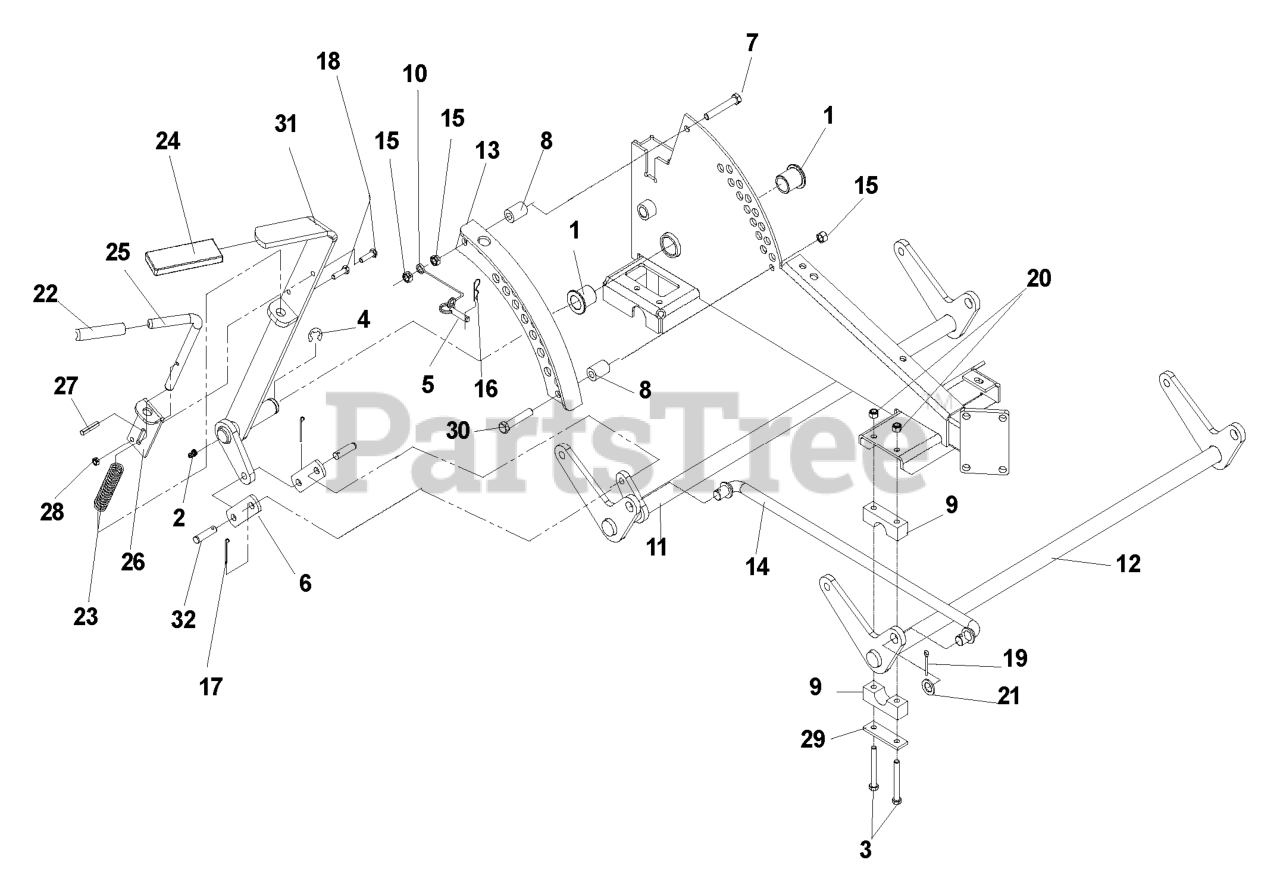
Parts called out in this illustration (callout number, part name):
1	BUSHING, FLANGED
2	ZERK
3	HCS 5/16C X 2-3/4
4	E-RING 7/8
7	SCREW 3/8C X 2 3/4 HEX CAP
8	DECK LIFT SPACER
9	PILLOW BLOCK
11	REAR LIFT SHAFT
12	FRONT LIFT SHAFT
13	ADJUSTMENT PLATE WLDMT
14	CROSS LINK
15	NUT 3/8-16 NYLOC
16	HAIRPIN #4
17	RP_COTTER PIN 1/8 X 3/4
18	HCS 1/4C X 3/4 HCS
19	COTTER PIN
20	NUT 5/16 NYLOC
21	BUSHING
26	PIN MT, UPPER
28	NUT 1/4C CENTER LOCK
29	REINFORCEMENT BAR
30	HCS 3/8C X 2 1/2
31	LIFT LEVER WELDMENT
32	CLEVIS PIN 3/8 X 1 1/8
